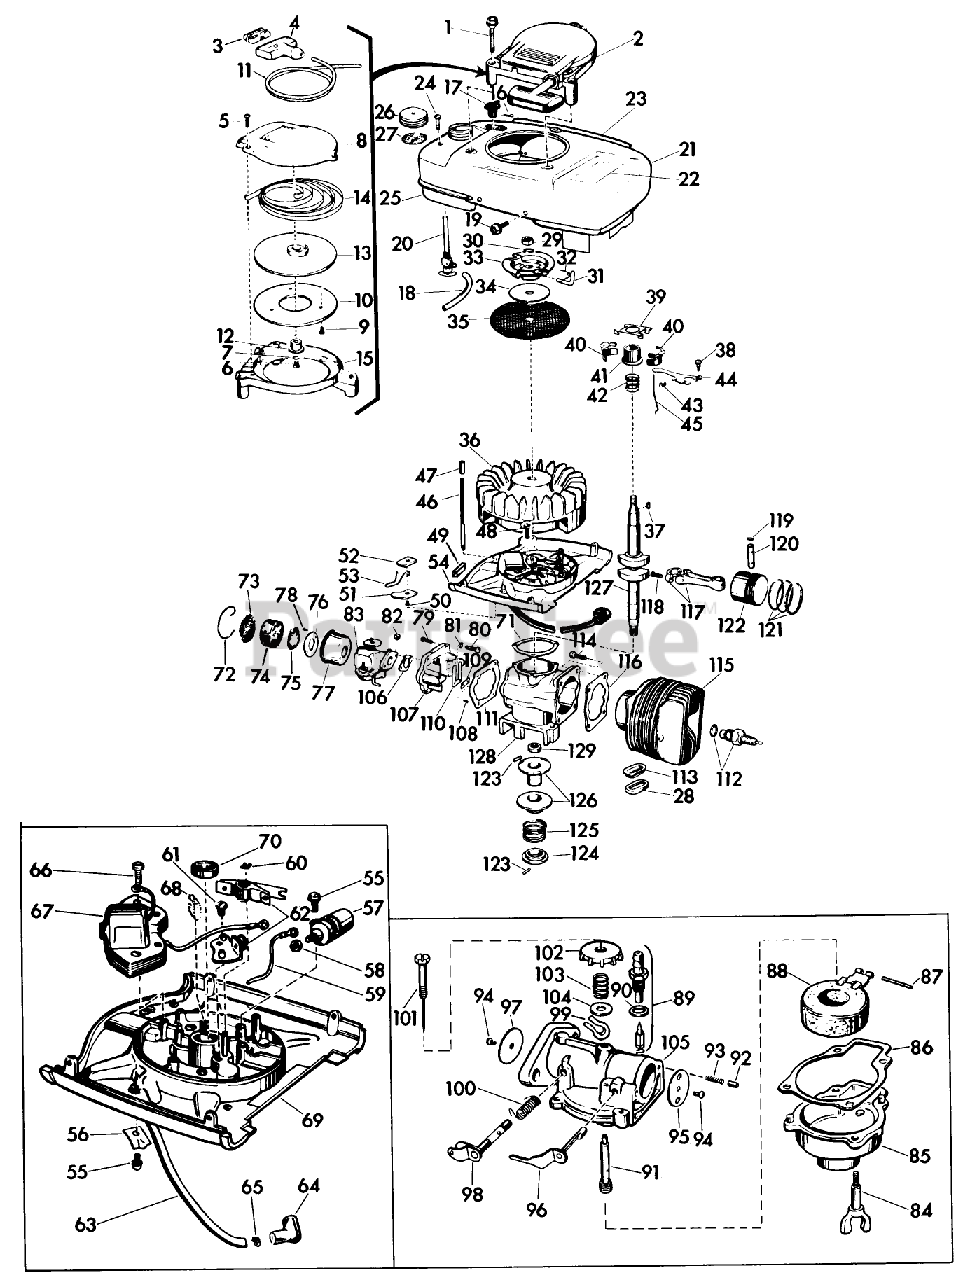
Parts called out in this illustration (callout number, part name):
14	RECOIL SPRING
15	Base-Starter
16	Cotter Pin-Choke Knob
17	KNOB, CHOKE BAR
19	SCREW S
20	VALVE&SCREEN SM
22	Decal-Instruction
23	Decal-"Lawn-Boy"
26	Gas Cap
31	PIN - STARTER
41	COLLAR S
43	WEAR BLOCK S
44	GOVERNER LEVER AY
45	GOVERNOR ROD S
50	Screw Shut-off Switch
60	Spring Clip-Breaker Post
62	BREAKER AY. S
64	Cover-Rubber
68	Oiler Wick
71	GASKET S
74	ELEMENT
76	BACK-UP PLATE
79	SCREW S
82	STOP NUT
94	Screw-Choke Disc
96	CHOKE SHAFT&LVR AY
100	SPRING
101	NEEDLE AY. S
103	Spring-Ndl. Adj.
106	GASKET S
109	PLATE-BACKUP, REED
112	Spark Plug
118	Screw-Connecting Rod
123	Pin-Pulley Drive
124	Retainer-Spring (Drive Pulley)
125	Spring-Comp. (Drive Pulley)
127	Crankshaft
